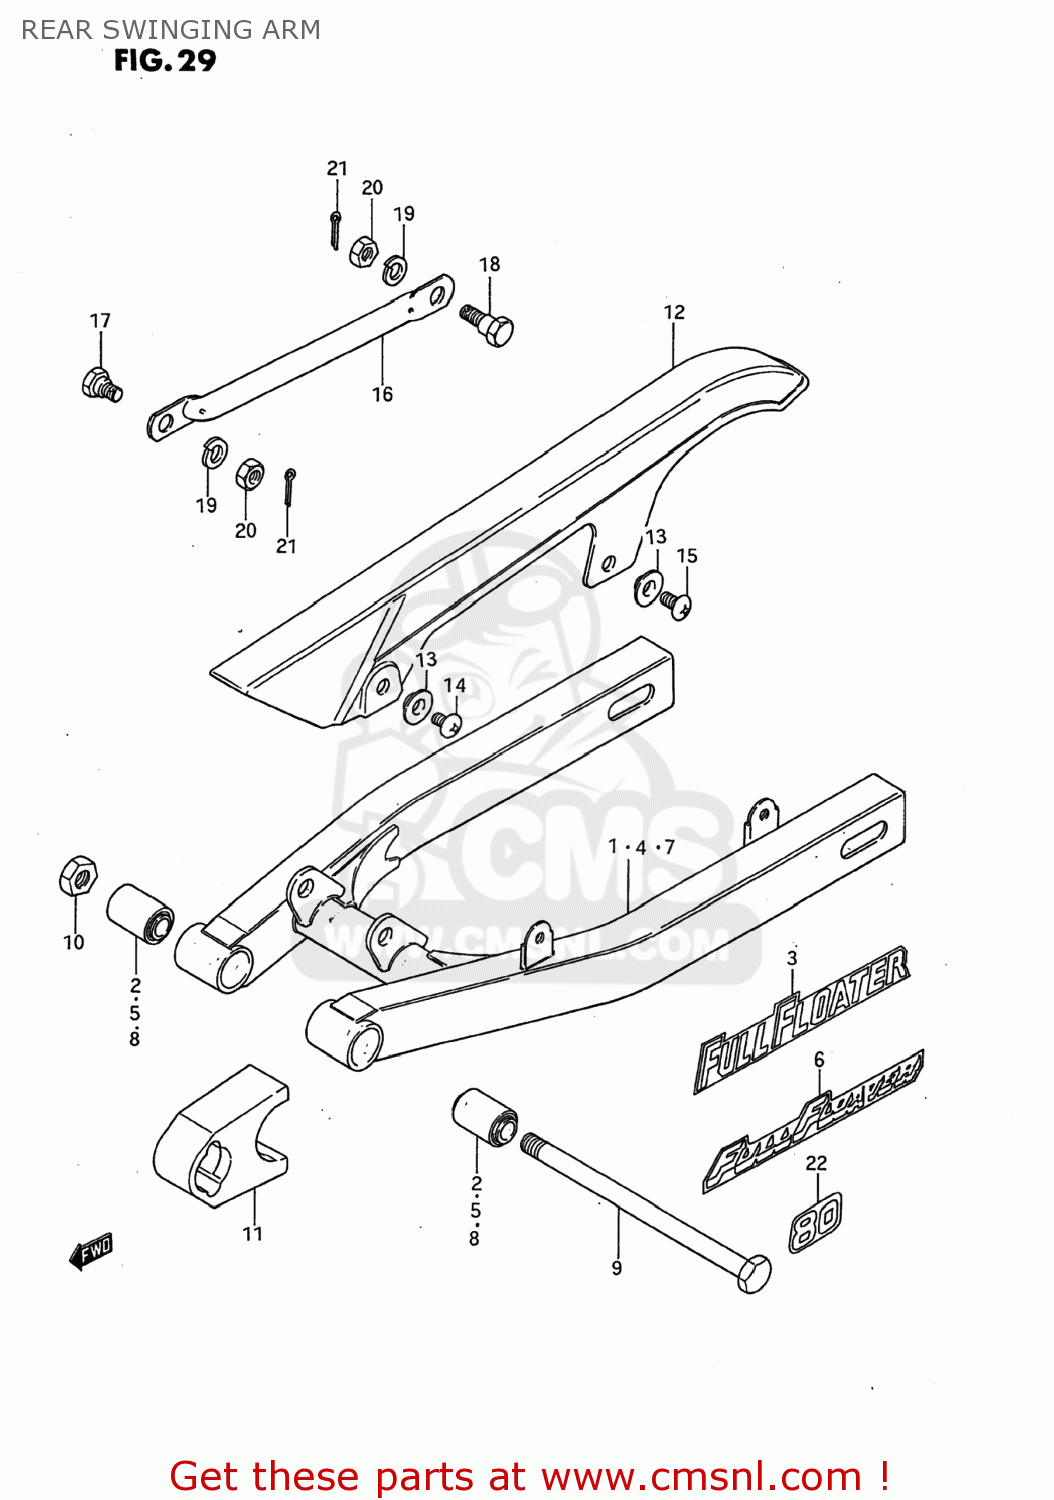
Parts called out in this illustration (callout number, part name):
1	SWING ARM ASSEMBLY,REAR
2	BUSH
3	EMBLEM
4	SWING ARM ASSEMBLY,REAR
5	BUSH
6	EMBLEM,SWING ARM
7	SWINGINGARM ASSY,RR
8	BUSH
9	SHAFT,RR SWINGINGARM PIVOT
10	NUT
11	BUFFER,CHAIN TOUCH DEFENSE
12	CASE,CHAIN
13	WASHER
14	SCREW
15	SCREW
16	TORQUELINK,RR
17	BOLT(8X22)
18	BOLT(8X26.5)
19	LOCK WASHER
20	NUT
21	PIN 20X20
22	EMBLEM,SWING ARM
